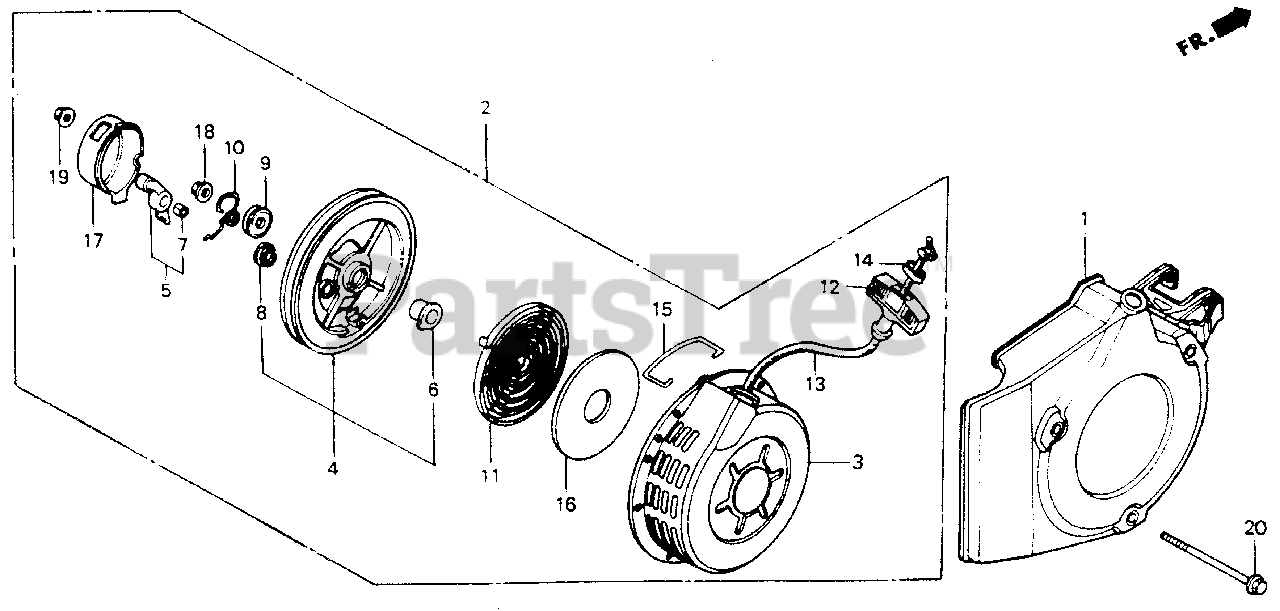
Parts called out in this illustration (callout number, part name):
1	COVER, RECOIL *R8* (BRIGHT RED) (NOT AVAILABLE)
2	STARTER ASSY., RECOIL (NOT AVAILABLE)
3	CASE, STARTER
4	REEL, STARTER
6	BOSS, REEL
7	BUSH, RATCHET
8	BUSH, REEL STARTER
9	PLATE, FRICTION
10	SPRING, FRICTION
11	SPRING, RETURN
12	GRIP, STARTER
13	ROPE, STARTER (#6X64")
14	SUPPORT, GRIP
15	HOLDER, ROPE
16	PLATE, SIDE
17	COVER, REEL STARTER
18	NUT, SELF-LOCK (8MM)
19	NUT, SELF-LOCK (6MM)
20	BOLT, FLANGE (6X70)
